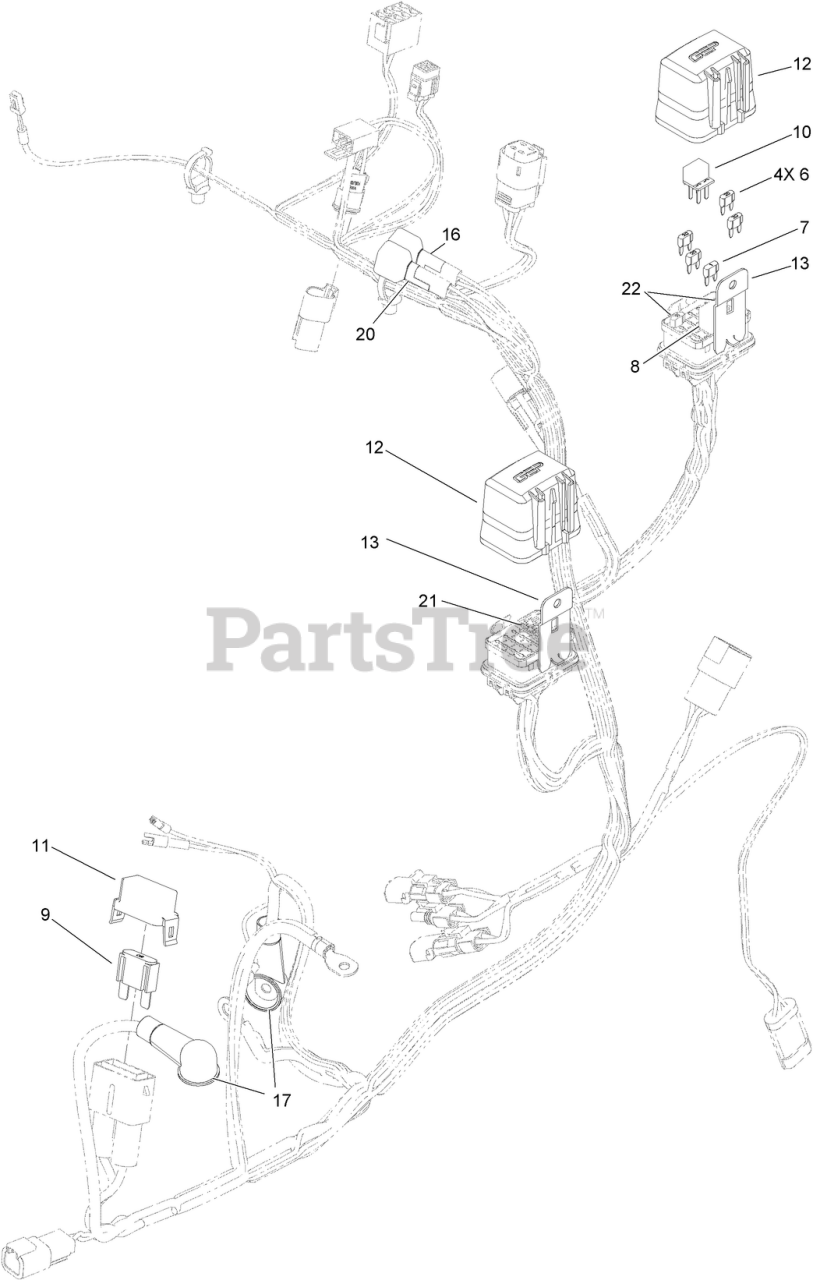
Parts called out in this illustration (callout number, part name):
6	FUSE-MINI BLADE, 20 AMP
7	Fuse-Mini Blade, 1 Amp
8	RELAY-MICRO
9	FUSE-MAXI, 60 AMP
10	Relay-Coil, NC, Mp280
11	Cover-Fuse Holder, Maxi
12	Cover-Fuseblock, 24F, Gep
13	CLIP-MOUNTING
17	Insulator-Lug, Red
21	PCA-HIGH POWER SSR
22	FUSE-MINI BLADE, 15 AMP
